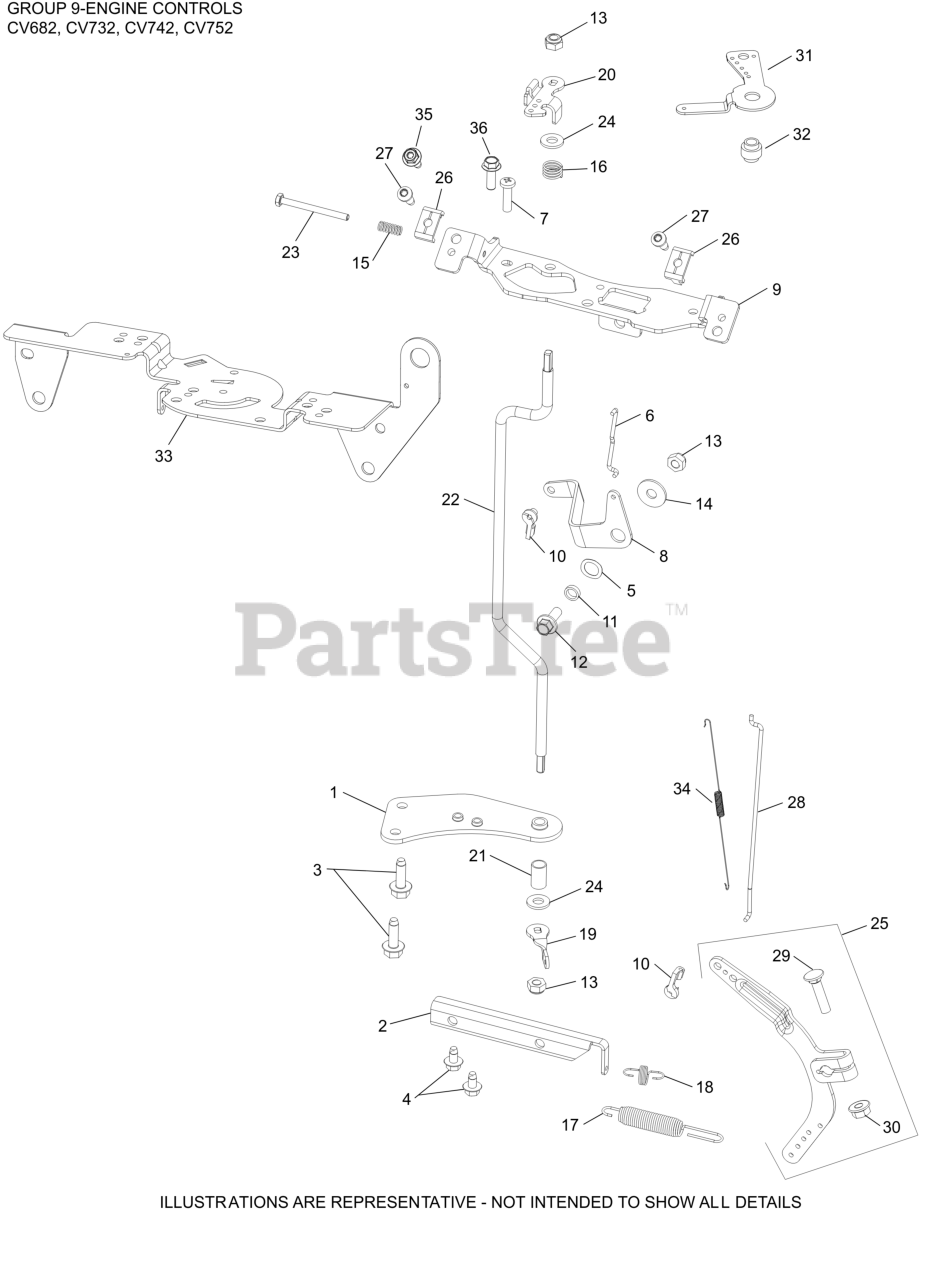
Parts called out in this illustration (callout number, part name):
1	BRACKET, THROTTLE SHAFT
2	BRACKET, GOVERNED IDLE
3	SCREW, THREAD FORMING
4	SCREW, THREAD FORMING
5	WASHER, SPRING 3/8"
6	LINKAGE, CHOKE
8	LEVER, CHOKE
9	BRACKET, CONTROL
10	BUSHING, THROTTLE LINKAGE
12	SCREW, FLG M6X1.0X16
13	NUT, LOCK M6X1.0
14	WASHER, FLAT 1/4"
16	SPRING, THROTTLE SHAFT
17	SPRING, GOVERNOR (RED)
18	SPRING, GOVERNED IDLE
19	LEVER, THROTTLE CONTROL
20	LEVER, THROTTLE CONTROL
22	SHAFT,CONTROL
23	SCREW, HEX HEAD
24	WASHER, FLAT 1/4"
25	LEVER, GOVERNOR - (#2409069S)
25	LEVER, GOVERNOR ASSEMBLY
26	CLAMP, CABLE
28	LINKAGE, THROTTLE
29	BOLT, RD HD SQ NECK M6X1.0X25
30	NUT, FLG M6X1.0
34	SPRING, LINKAGE
35	SCREW, THREAD FORMING
36	SCREW, HI-LOW
